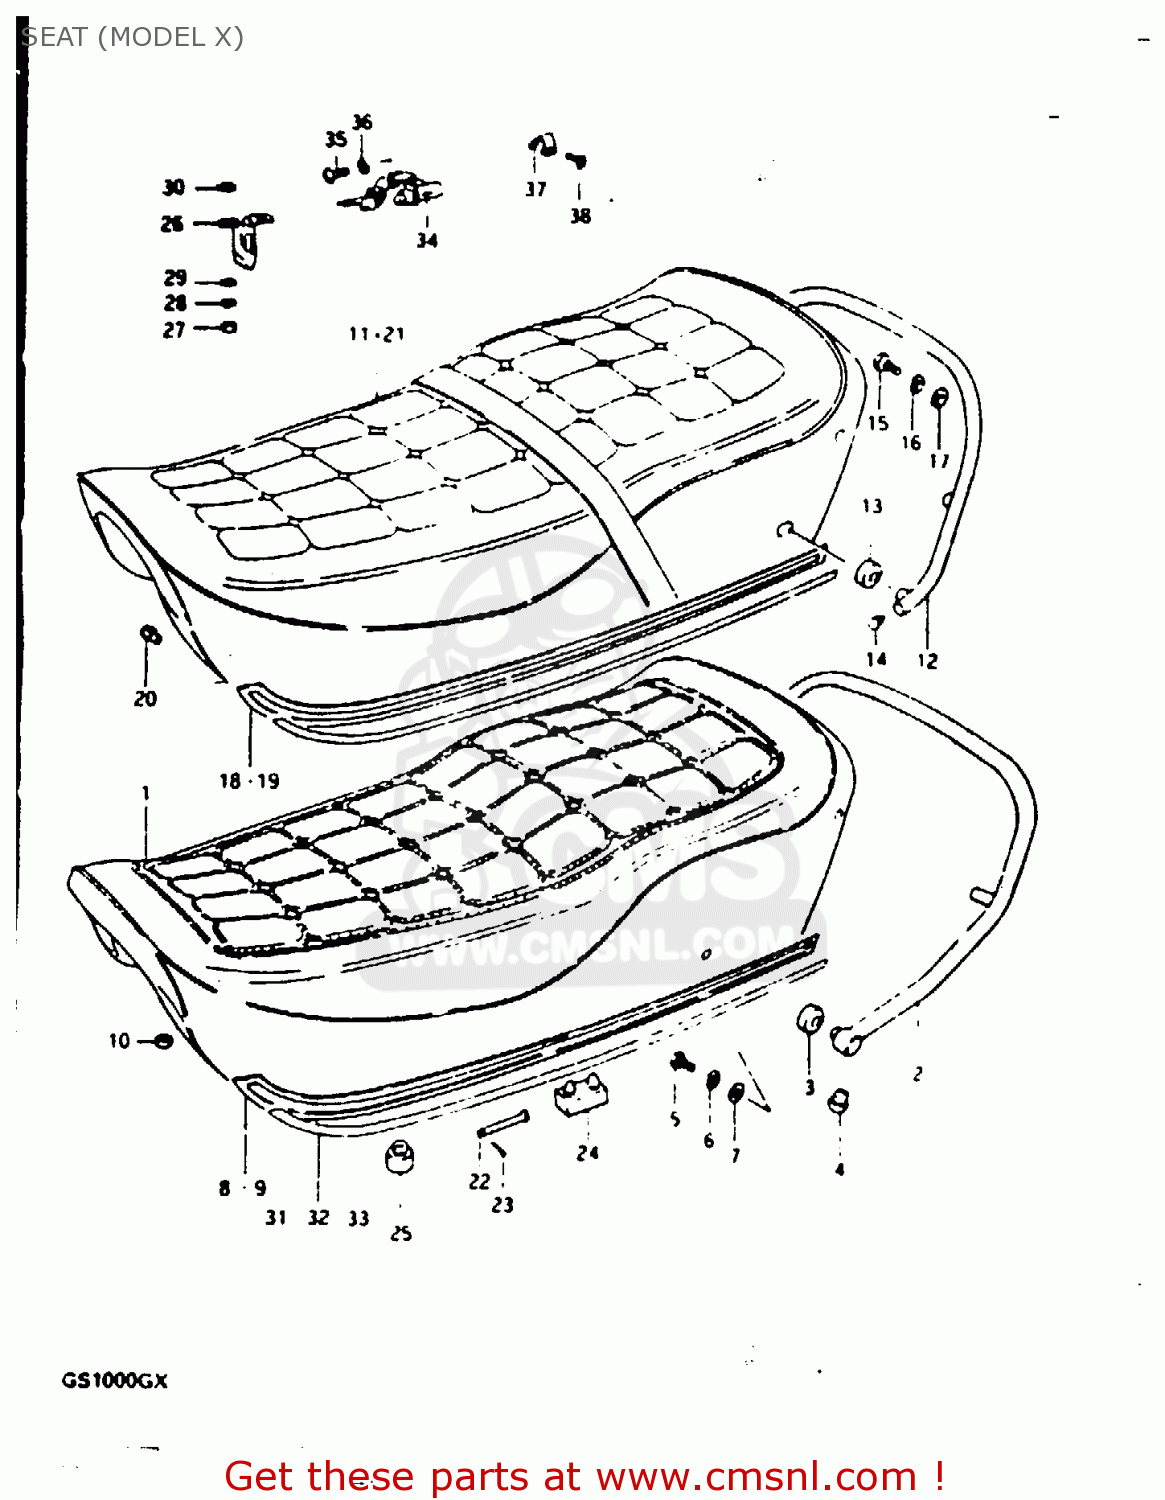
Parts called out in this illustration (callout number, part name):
11	SEAT ASSY
12	HANDLE, PILLION RIDER
13	CUSHION
14	END,SHEET HANDLE
15	BOLT
16	LOCK WASHER
17	WASHER
18	MOLE,R
19	MOLE,L
20	NUT
21	SEAT ASSY
22	PIN
23	PIN
24	CUSHION
25	CUSHION
26	STRIKER,SEAT LOCK
27	NUT
28	LOCK WASHER
29	WASHER 6MM
30	WASHER (6.5X20X1.2)
31	TAPE SET
32	TAPE SET, SEAT MOULDING
33	TAPE SET, SEAT MOULDING
34	LOCK ASSY,SEAT
35	SCREW
36	LOCK WASHER
37	SPRING,HELMET HOLDER
38	SCREW
